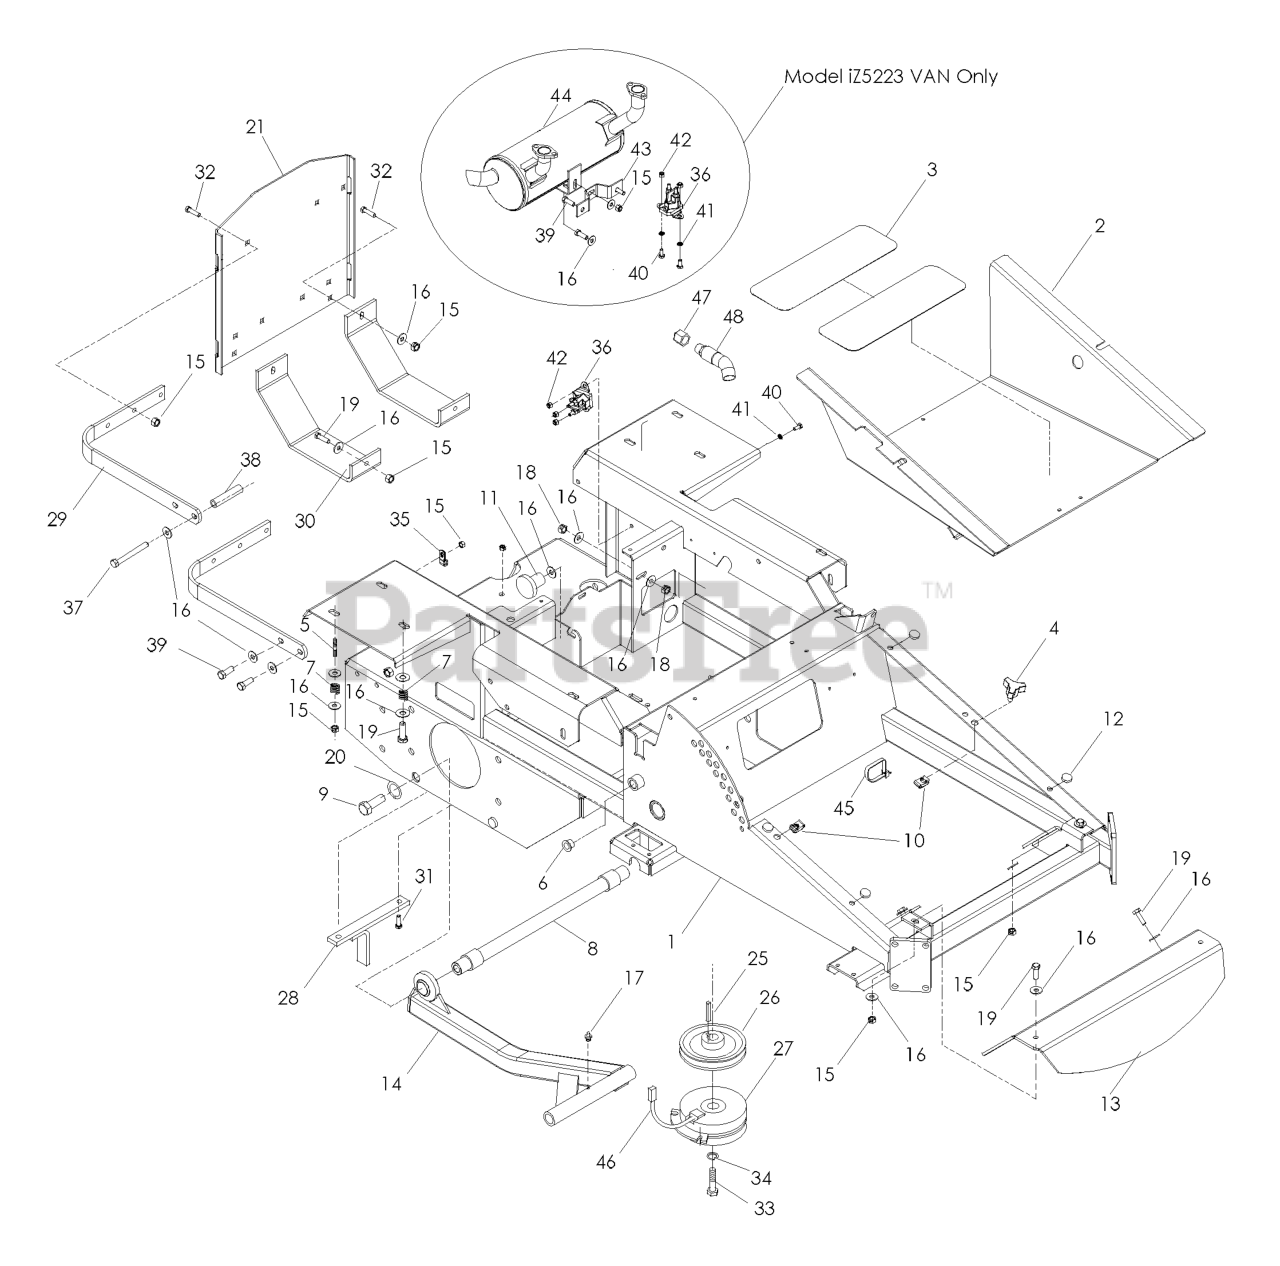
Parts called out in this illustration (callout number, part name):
1	IZ FRAME W/DECALS
2	IZ FOOTPLATE W/DECAL
3	ANTI-SKID PAD
4	KNOB W/STUD
5	STUD, 5/16C
8	STRUT MOUNT WELDMENT
9	HCS 5/8C X 2 GR.5
10	U-CLIP 5/16-18 NUT RETAINER
12	GROMMET, BUMPER
13	FOOTREST ORANGE
15	NUT 5/16 NYLOC
16	WASHER 5/16 FLAT
17	ZERK
18	NUT 5/16C CENTERLOCK
19	HCS 5/16C X 1
20	LOCKWASHER 5/8
21	ENGINE GUARD
21	REAR GUARD
22	SCREW 3/8C X 3/4 HEX CAP
23	WASHER 3/8 FLAT
24	NUT 3/8-16 NYLOC
25	KEY, 1/4 SQ X 1 1/4
28	ELECTRIC CLUTCH W/CABLE
28	CLUTCH-200 FT LB(RPLS 5218-102
29	CLUTCH TIE DOWN
30	ENGINE SHROUD BRKT
31	SKID PLATE
32	HCS 5/16C X 1 3/4
33	RHSSNB 5/16C X 1.0
34	BOLT 7/16F X 2 1/2
35	HCS 7/16-20 X 2-3/4
36	WASHER 7/16 LOCK
37	DOUBLE TUBE CLAMP
39	HCS 5/16C X 4
41	HCS 5/16C X 1
42	HCS 1/4C X 5/8
43	WASHER 1/4 INT TOOTH
44	NUT.1/4-20.HEX.NYLOC.ZD
45	BRACKET, MUFFLER
46	MUFFLER VANGUARD 23HP
47	TIE, PLASTIC
48	CLUTCH HARNESS
50	OIL DRAIN HOSE
